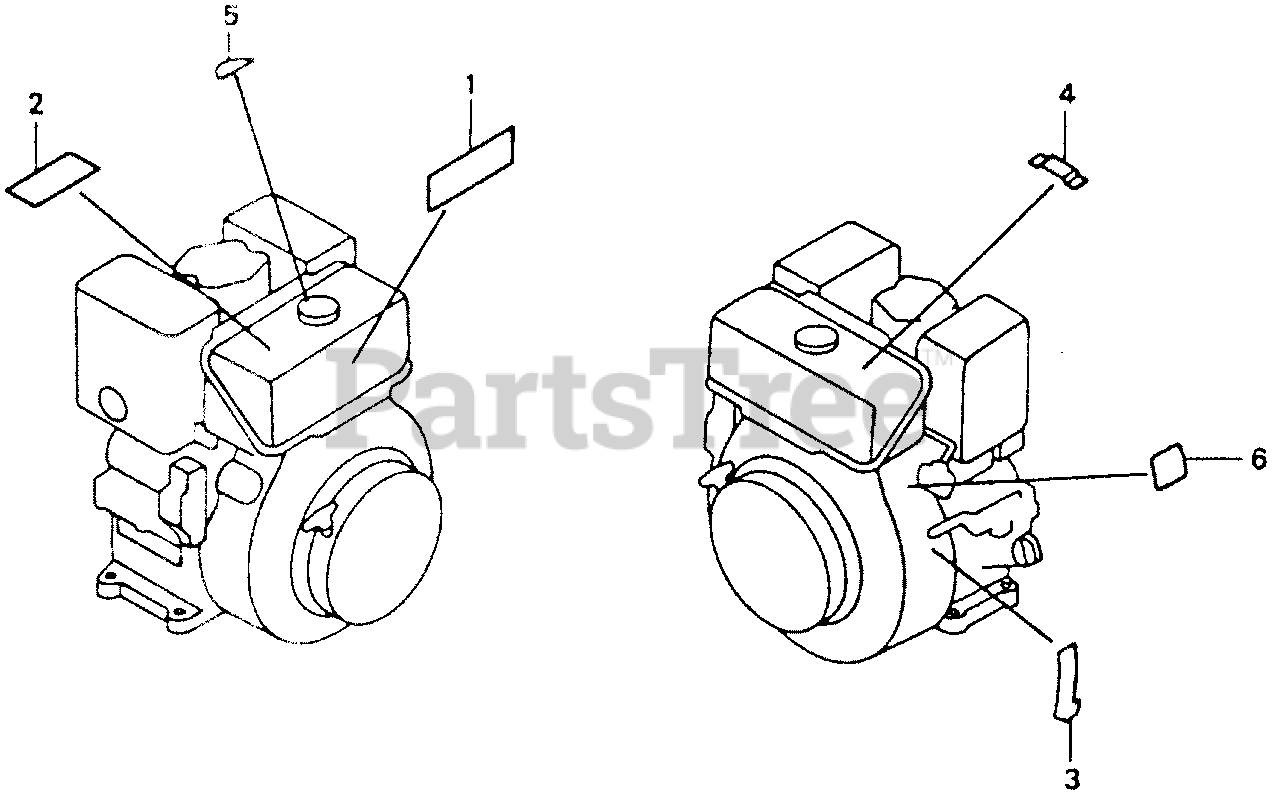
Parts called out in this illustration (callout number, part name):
1	EMBLEM (GD410)
2	LABEL, CAUTION (E.F.G.S)
3	MARK, THROTTLE (E)
4	MARK, FUEL (EXTERNAL)
5	MARK, USE FUEL (E)
6	MARK, OIL CAUTION (E)
